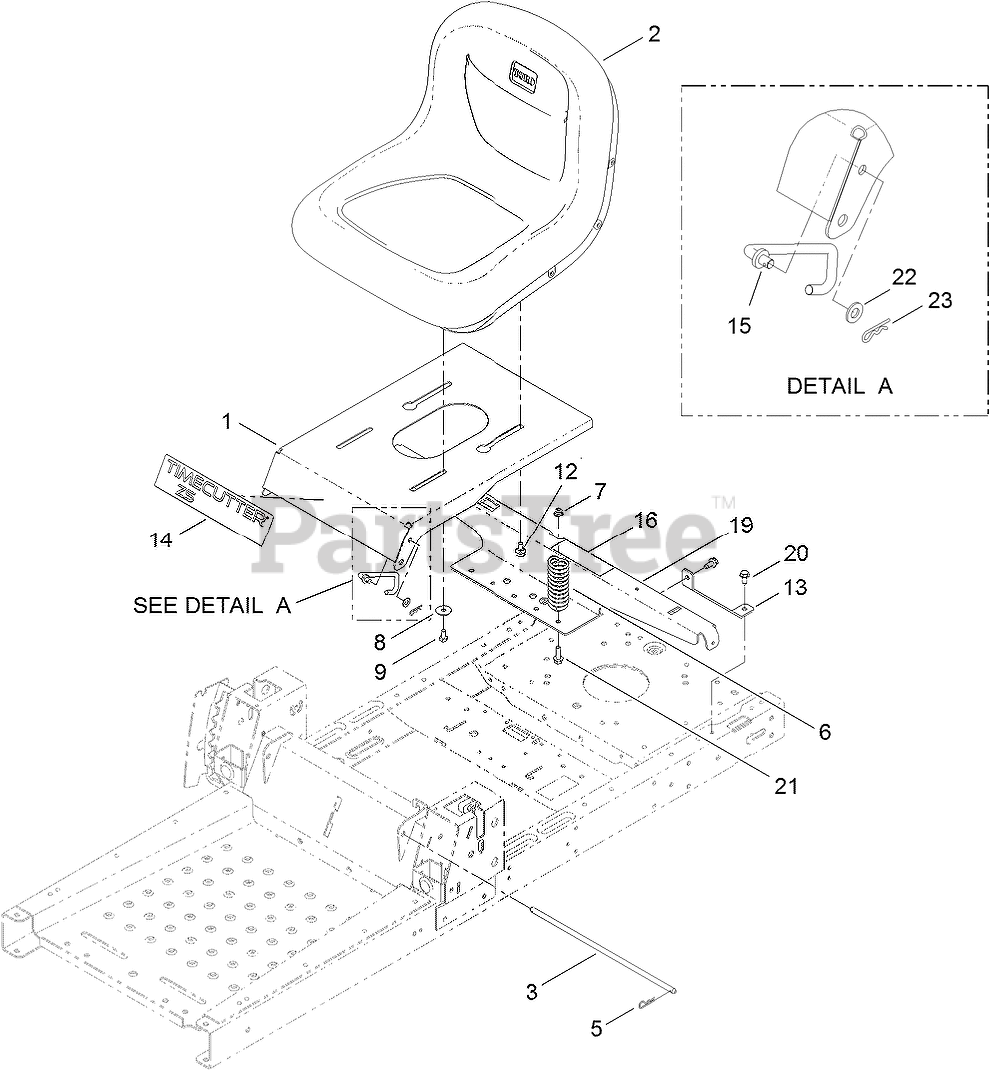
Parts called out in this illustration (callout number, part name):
1	PAN-SEAT
2	SEAT-15 INCH
3	ROD-PIVOT, NARROW
5	PIN-COTTER
6	SPRING-COMPRESSION
7	NUT-HF, NI
8	WASHER-PIVOT
9	SCREW-HH
12	BOLT-SHOULDER
13	SUPPORT-TANK, REAR
14	DECAL-TIMECUTTER
15	STOP-SEAT
16	DECAL-SERVICE, CE
19	SUPPORT-POD
20	SCREW-HWHTF
21	SCREW-HHF
22	WASHER-PLAIN
23	PIN-COTTER
